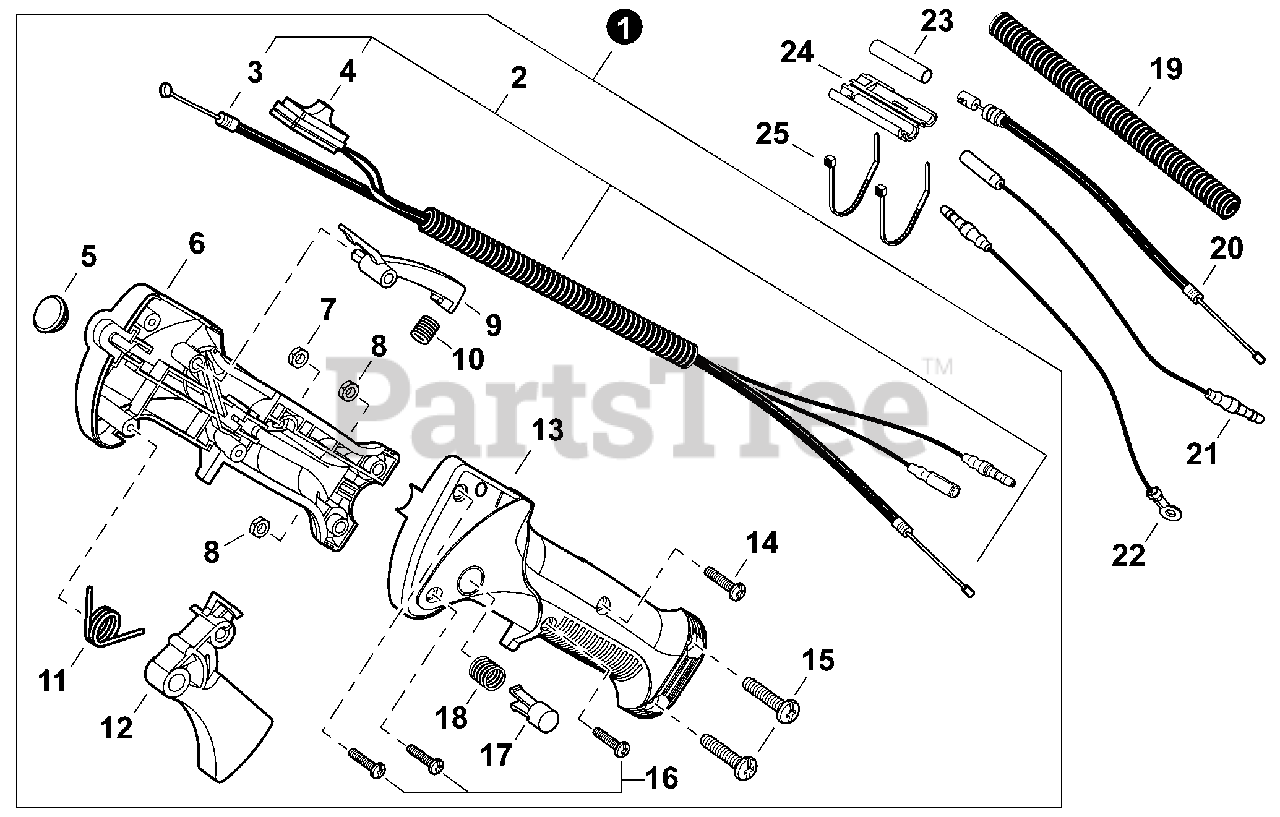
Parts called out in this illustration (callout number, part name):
1	THROTTLE CONTROL ASSY
2	CABLE ASSY, CONTROL
3	CABLE, THROTTLE
4	SWITCH, ON-OFF
5	PLUG, RUBBER
6	CONTROL HANDLE - RIGHT
7	NUT M4
8	NUT M5
9	LOCKOUT, THROTTLE
10	SPRING, COMPRESSION
11	SPRING, TORSION
12	TRIGGER, THROTTLE
13	CONTROL HANDLE - LEFT
14	SCREW M4x23
15	SCREW M5x20
16	SCREW, TAPPING 4x16
17	BUTTON, THROTTLE LOCK
18	SPRING, COMPRESSION
19	TUBE, FLEXIBLE
20	CABLE, THROTTLE
21	LEAD - IGNITION
22	LEAD - GROUND
23	SLEEVE
24	CAP, DUST
25	TIE, CABLE
